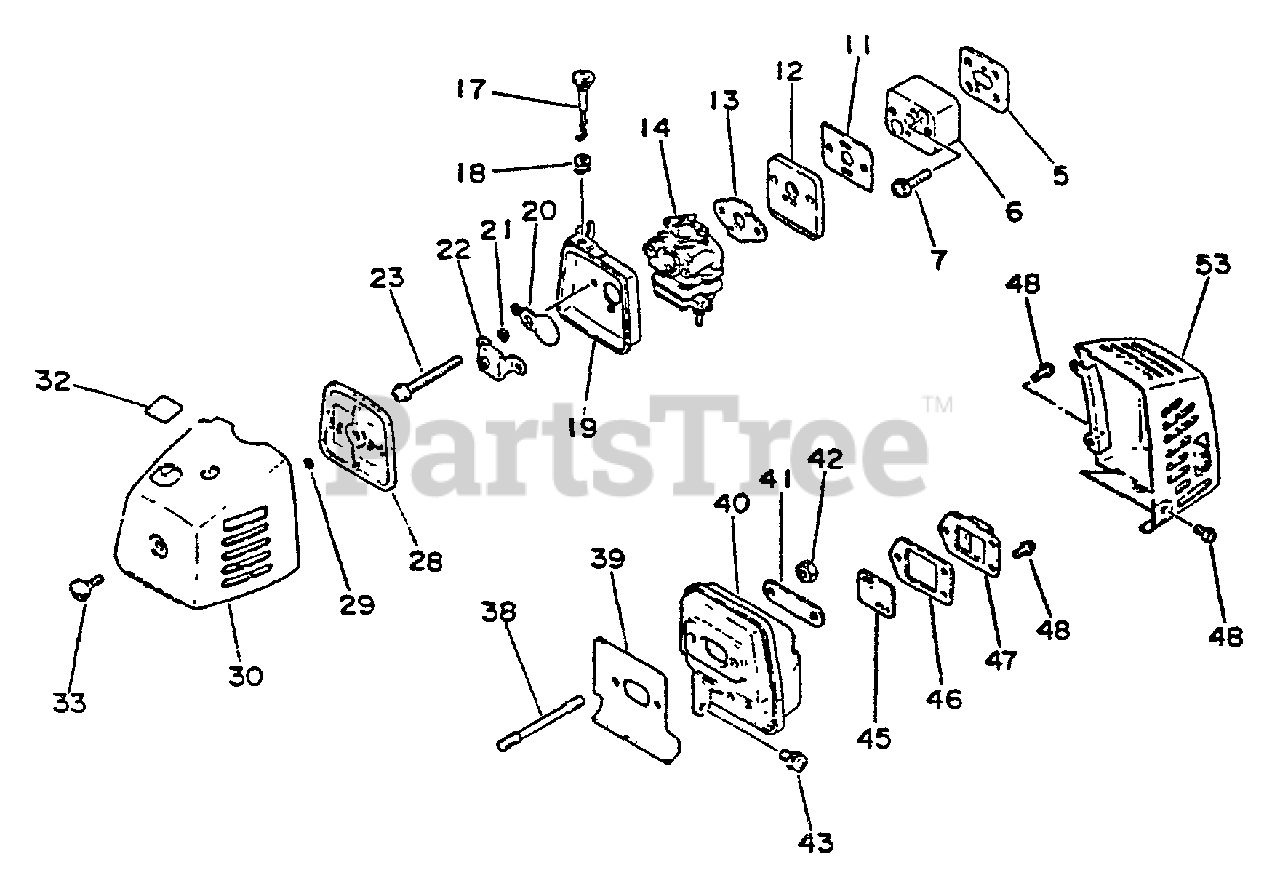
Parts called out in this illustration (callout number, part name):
5	GASKET, INTAKE
6	INSULATOR, INTAKE
7	SCREW - 5X22
11	GASKET, INTAKE
12	PLATE
13	GASKET, INTAKE
14	CARBURETOR
17	ROD, CHOKE
19	CASE, AIR FILTER
20	SHUTTER, CHOKE
21	WASHER - 5
22	PLATE, PREVENT
23	SCREW - 5X50
28	FILTER, AIR
29	O-RING - 4
30	AIR FILTER COVER ASSY
32	LABEL - CHOKE
38	STUD - 5X60
39	GASKET, EXHAUST
40	MUFFLER
42	LOCKNUT - 5
43	SCREW - 5X10
45	SCREEN, SPARK ARRESTOR
46	GASKET, EXHAUST
47	GUIDE, EXHAUST
48	SCREW - 4X8
53	COVER, EXHAUST
